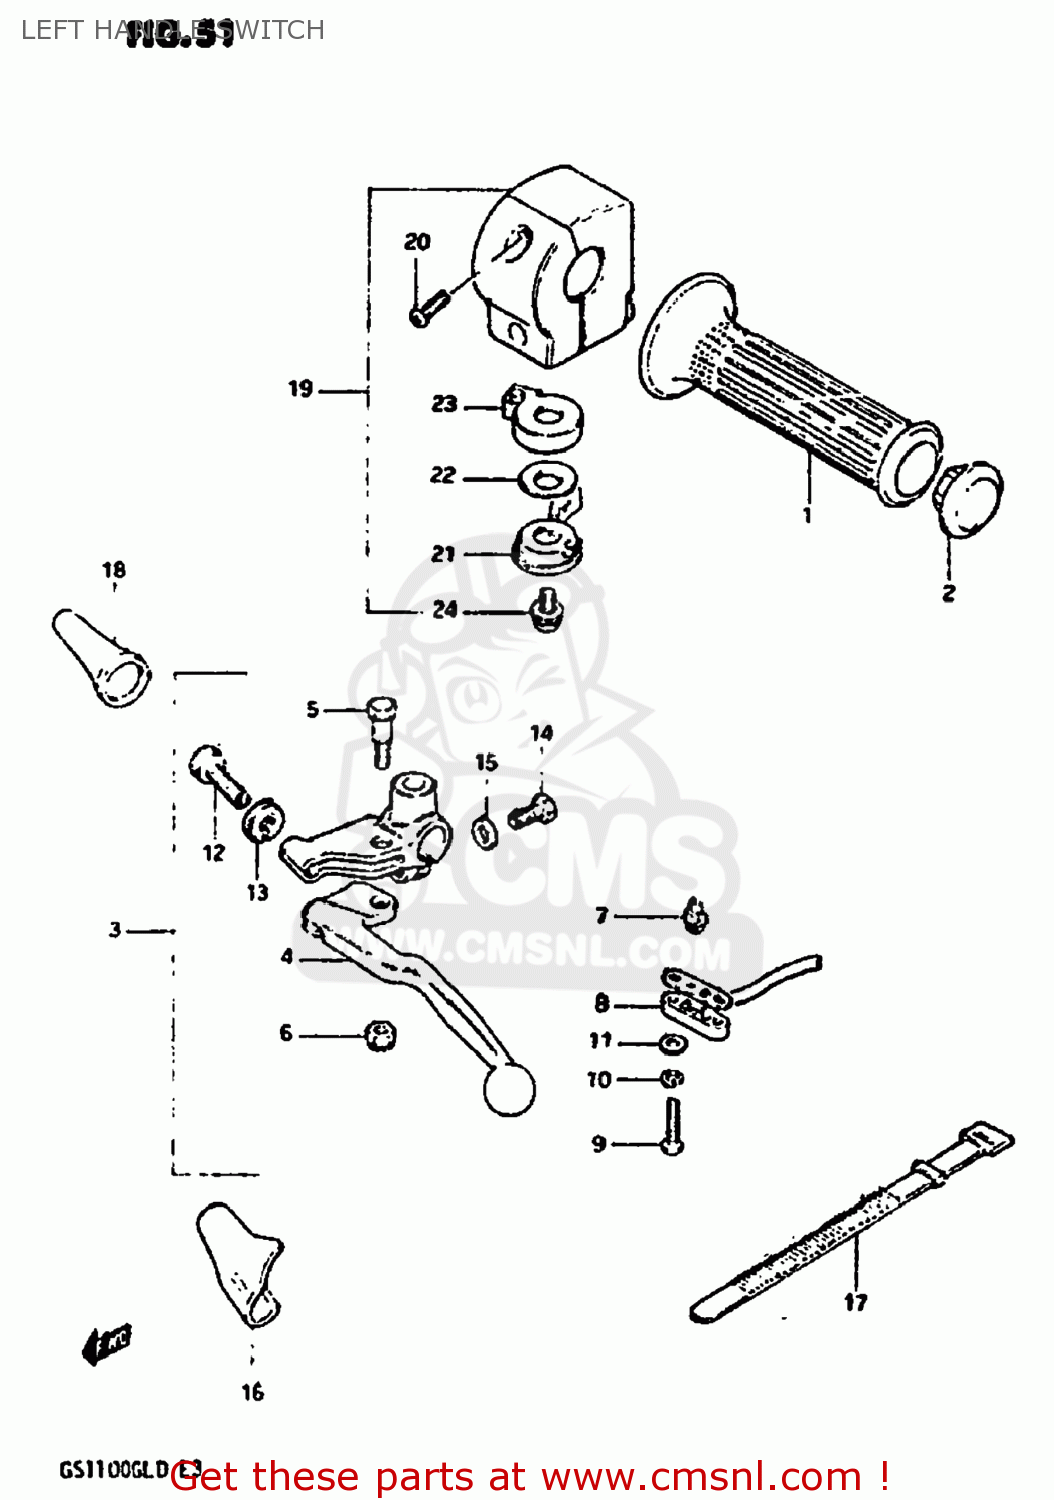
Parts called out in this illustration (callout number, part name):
1	GRIP,LEFT
2	CAP,GRIP END
3	LEVER ASSEMBLY
4	LEVER,CLUTCH
5	BOLT,LEVER
6	NUT 6MM
7	CONTACT,SWITCH
8	COVER,FR BK TERMINAL BASE
9	SCREW
10	LOCK WASHER
11	WASHER
12	ADJUSTER,CABLE
13	NUT,CABLE ADJUSTER
14	BOLT,CLUTCH LEVER HOLDER
15	WASHER
16	COVER,CLUTCH LEVER
17	CLAMP(L:120)
18	BOOT,CLUTCH CABLE
19	SWITCH ASSEMBLY,HANDLE,LEFT
20	SCREW
21	LEVER,STARTER
22	WASHER,ADJUSTER
23	BODY,CHOCK
24	SCREW,CHOKE LE
